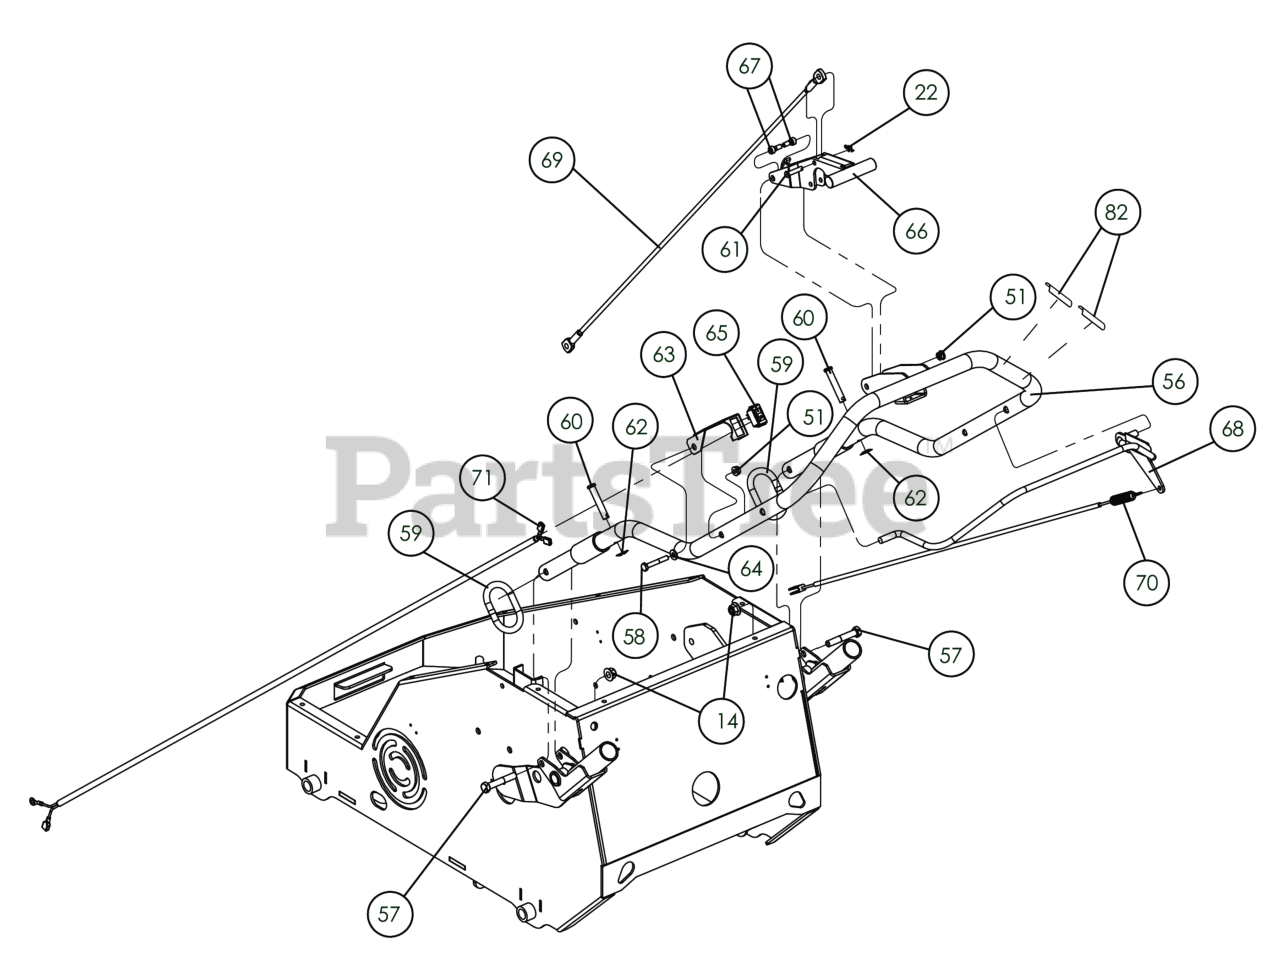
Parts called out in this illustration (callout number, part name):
14	NUT-HEX-NYLK, FLG .375"-16 ZP
22	1/4" RUE RING
51	NUT-HEX-NYLK, FLG .250"-20 ZP
56	WA, HANDLE PL1801
57	SCREWCAP 3/8"-16 X 2 1/4" HCS ZP GR 5
58	SCREWCAP 1/4"-20X1 3/4" HCS ZP
59	LOOP FOLDING HANDLE
60	PIN CLEVIS 3/8 X 2.125
61	CLEVIS PIN 1/4 X 1
62	RETAINER 3/8" BOLT PUSH NUT
63	BRACKET MOUNT SWITCH QB16SP
64	WASHER 1/4"SAE9/32"X5/8"X1/16"
65	SWITCH LKG RKR B&S #493521
66	RETRACTOR HANDLE (PL850)
67	SHOULDER BOLT, 5/16 DIA X 1/4
68	WA, BAIL PL1801
69	TINE LIFT CABLE, PL1801
70	CABLE CLUTCH 39"
71	HARNESS WIRE 60"
82	LABEL TINE ENGAGE PL
